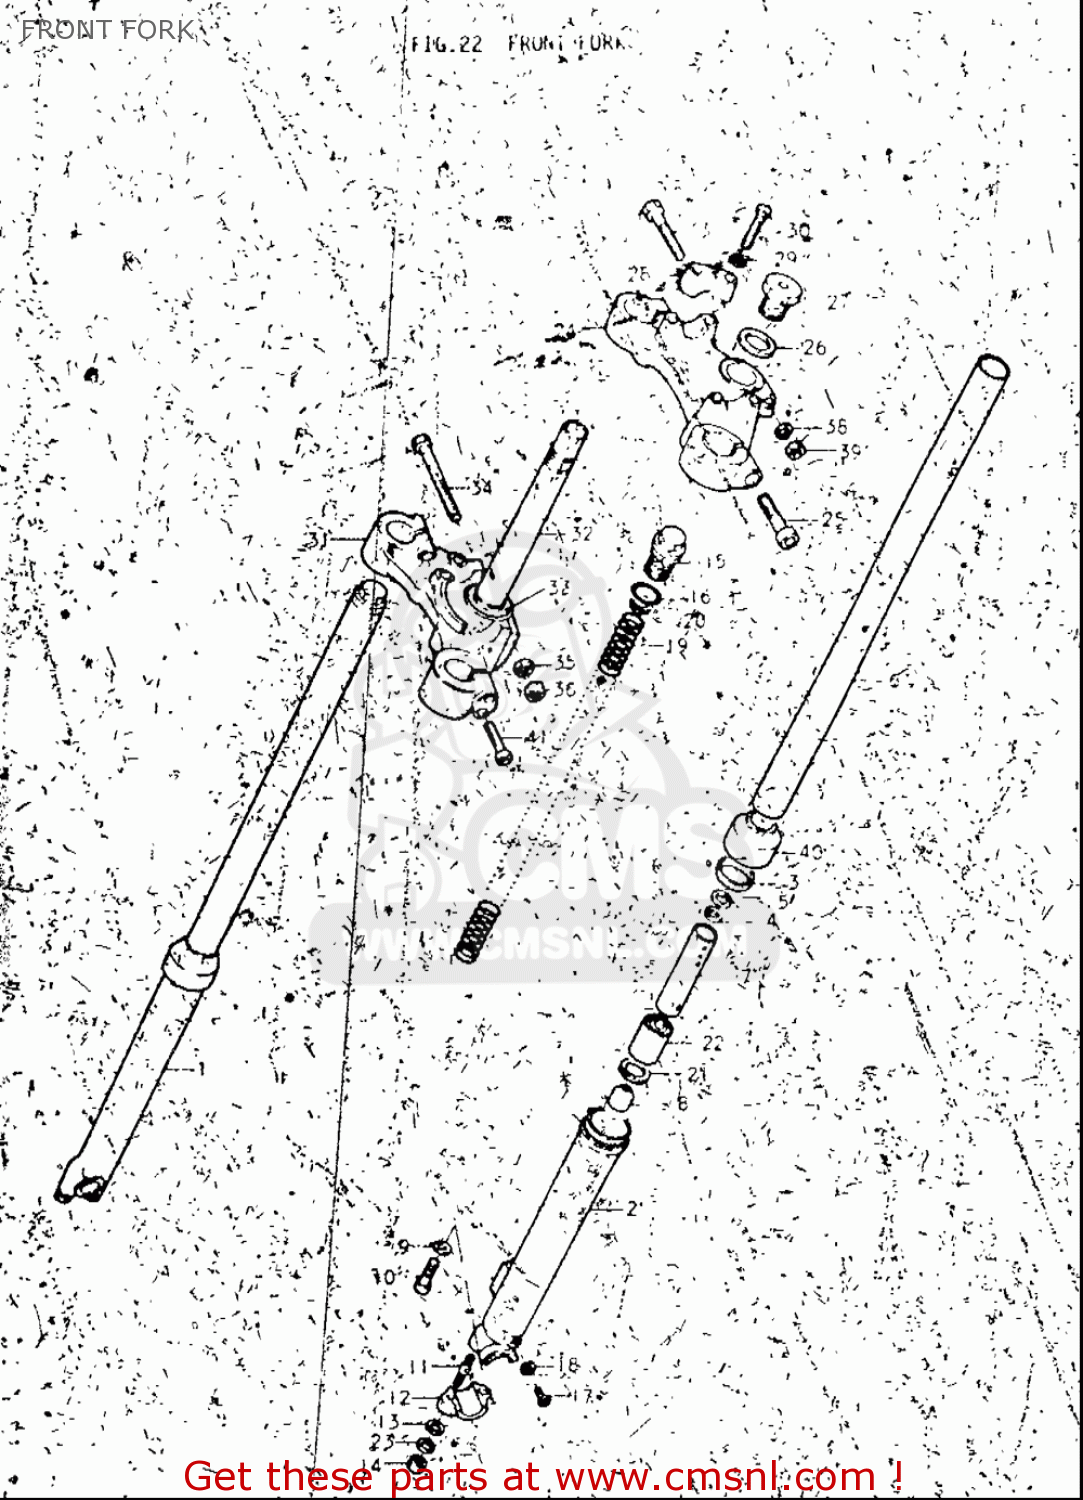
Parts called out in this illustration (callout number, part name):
3	SEAL,OIL
10	BOLT,FORK CYLINDER(10X25)
11	STUD BOLT
13	WASHER
14	NUT
16	O-RING,FORK FITTING BOLT
17	SCREW
18	GASKET,DRAIN,PLUG (NAS)
23	WASHER,LOCK
27	CAP
29	WASHER,LOCK
33	LACE,STEERING INNER LWR
34	BOLT
35	WASHER,LOCK
36	NUT
37	BOLT
38	WASHER,LOCK
39	NUT
41	BOLT
